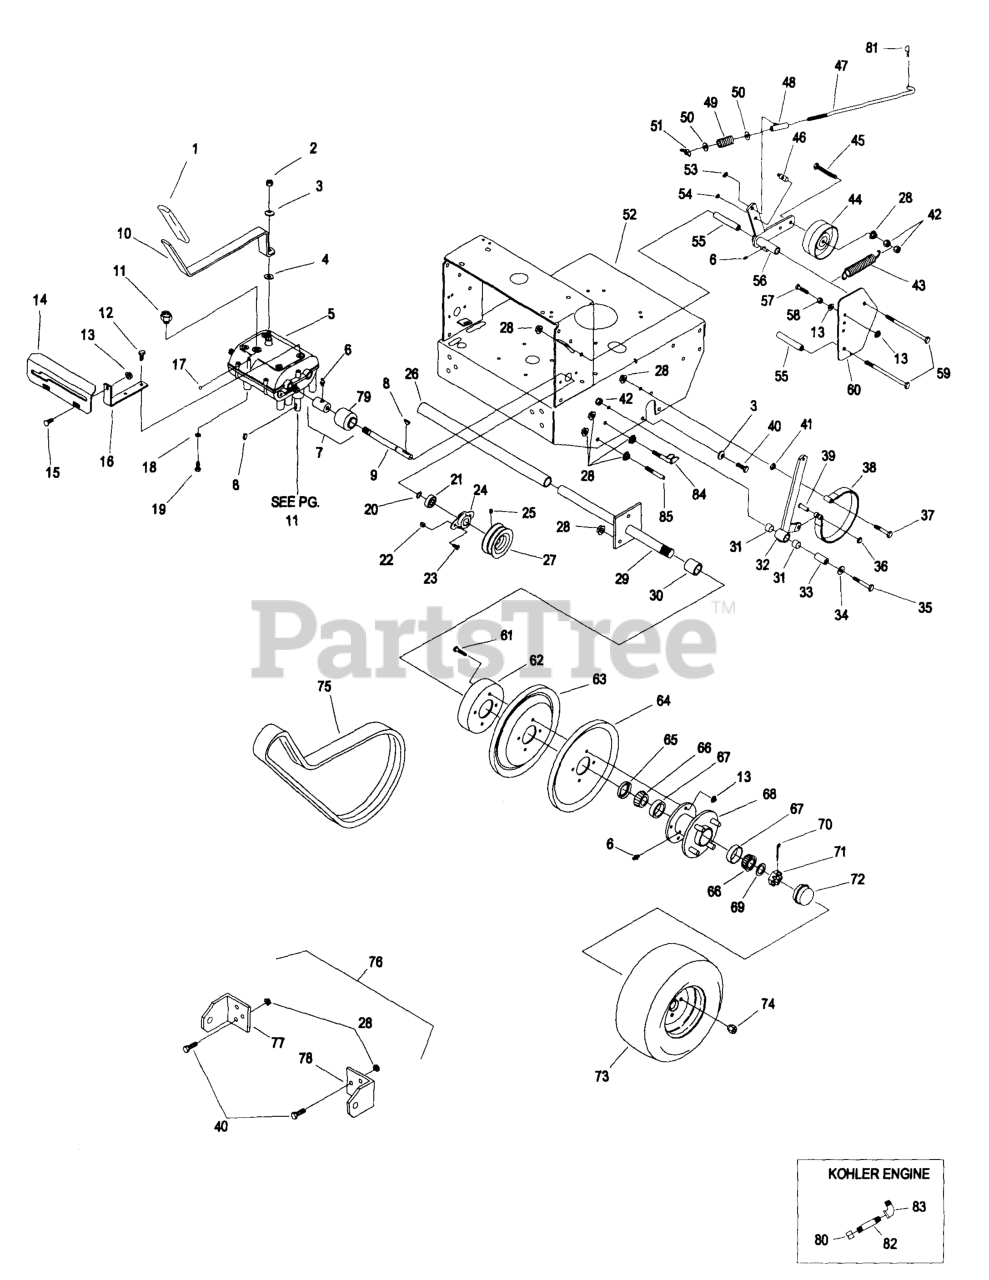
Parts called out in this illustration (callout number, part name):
7	ASM,COUPLER/ZERK
9	SHAFT-TRANSMISSION
11	SWITCH-START, NEUTRAL
16	BRACKET-PLATE, SHIFT
17	BALL,DETENT (SERVICE ONL
18	WASHER-LOCK
21	BEARING-SHAFT
24	FLANGE-OUTPUT
25	SCREW-SET
26	SLEEVE,AXLE
30	SPACER,WHEEL SHORT
31	SLEEVE-BUSHING
33	BUSHING-PIVOT
36	RING-RETAIN,PUSH,EXT,FLAT
38	BAND-BRAKE
39	PIN-CLEVIS
43	SPRING-EXTENSION
44	IDLER-WHEEL, DRIVE
46	SWIVEL-SHORT, ADJUSTABLE
47	LINKAGE-BRAKE
49	SPRING-COMPRESSION
51	WINGNUT-NYLOCK
52	Deck, Weldmt Engine
55	SPACER-SHIELD
56	WLD,ARM RH
60	SHIELD,WHEEL DRIVE
62	DRUM-BRAKE
63	SHEAVE,WHEEL DRIVE
64	SHEAVE,WHEEL DRIVE
65	SEAL-GREASE
66	Cone-Bearing Tapered Roller
67	CUP-BEARING
68	HUB/WHEEL ASM
69	WASHER-SPACER
70	PIN-COTTER
71	NUT-SHH
72	CAP-GREASE
73	WHEEL AND TIRE ASM
75	BELT,WHEEL DRIVE BANDED
76	Kit, Sulky Hitch
78	BRACKET,SULKY RH
80	CAP-HEX
81	PIN-COTTER
82	NIPPLE
83	FITTING-ELBOW-90
84	SCRAPER
